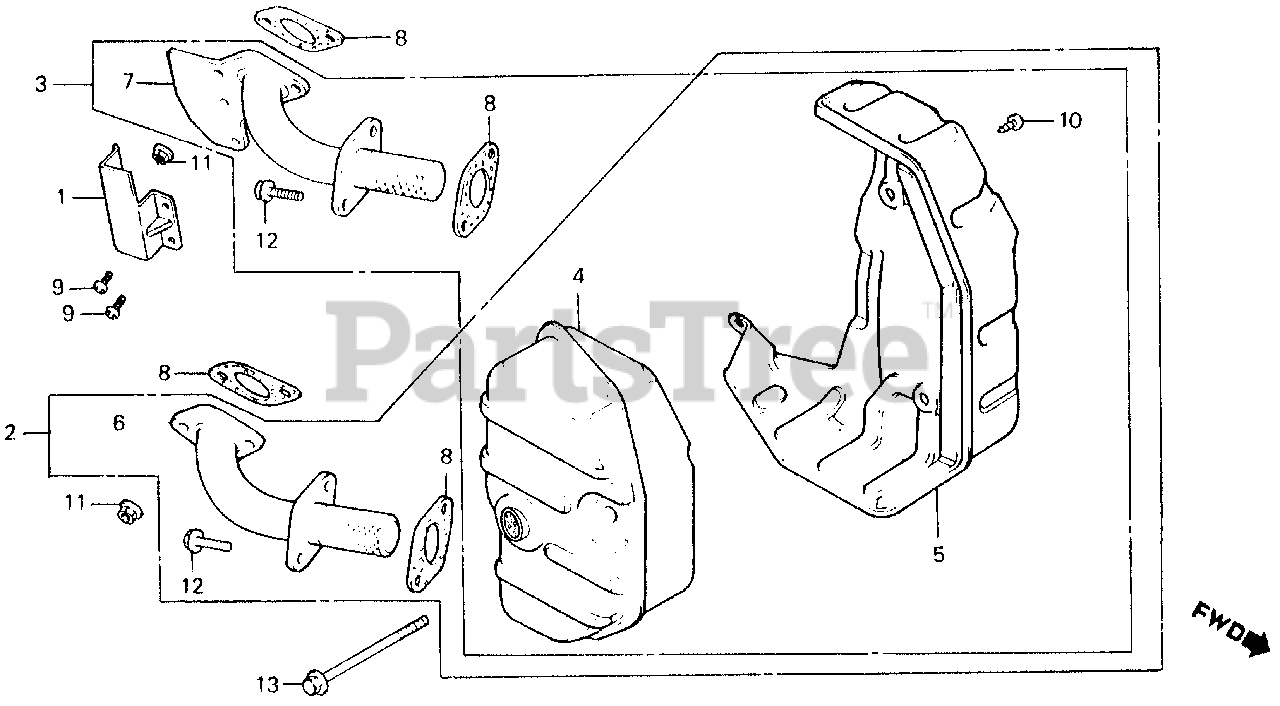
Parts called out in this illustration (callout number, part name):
1	COVER, BIMETAL
3	MUFFLER ASSY.
4	MUFFLER (NOT AVAILABLE)
5	PROTECTOR, MUFFLER
7	PIPE, EX. (NOT AVAILABLE)
8	GASKET, MUFFLER (NOT AVAILABLE)
9	SCREW, PAN (5X6)
10	SCREW, TAPPING (5X8) (NOT AVAILABLE)
11	NUT, FLANGE (6MM)
12	BOLT, FLANGE (6X16)
13	BOLT, FLANGE (6X65)
